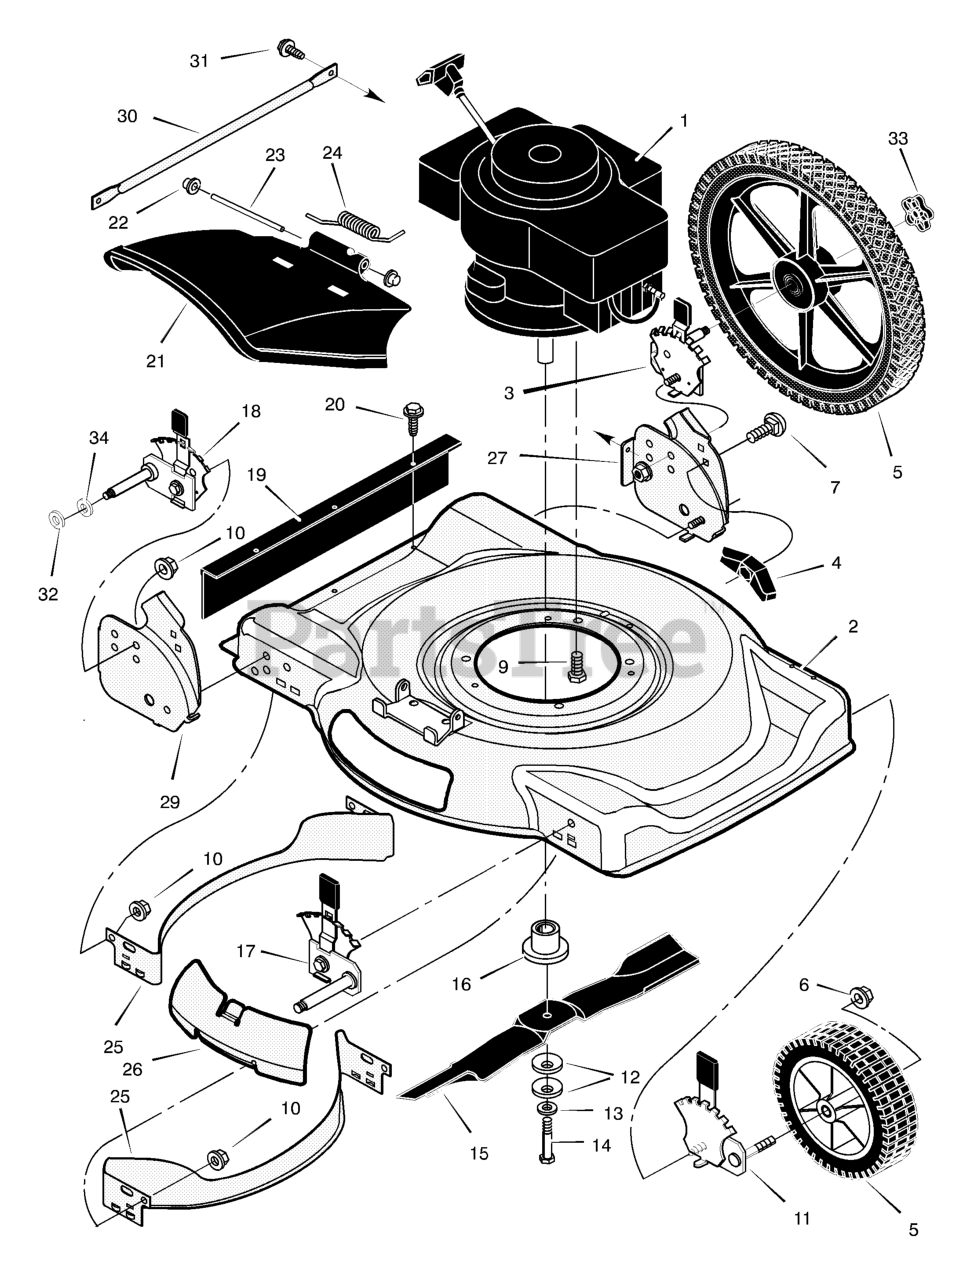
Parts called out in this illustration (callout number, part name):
1	Engine
2	Housing
3	Height Adjuster, Left Rear
5	Wheel and Tire - Front
5	Wheel and Tire - Rear
6	Locknut, Flange
7	Bolt, Carriage
9	Bolt, Engine
10	Nut
11	Height Adjuster, Left Front
12	Washer, Belleville
14	Bolt, Hex
16	Adapter, Blade
17	Height Adjuster, Right Front
18	Height Adjuster, Right Rear
19	Guard, Rear
20	Screw
21	Deflector, Chute
22	Push-On Cap
23	Pin, Pivot
24	Spring
26	Plate, Mulcher
27	Bracket, Left Handle
29	Bracket, Right Handle
33	Knob, Axle
34	Washer, Spring
